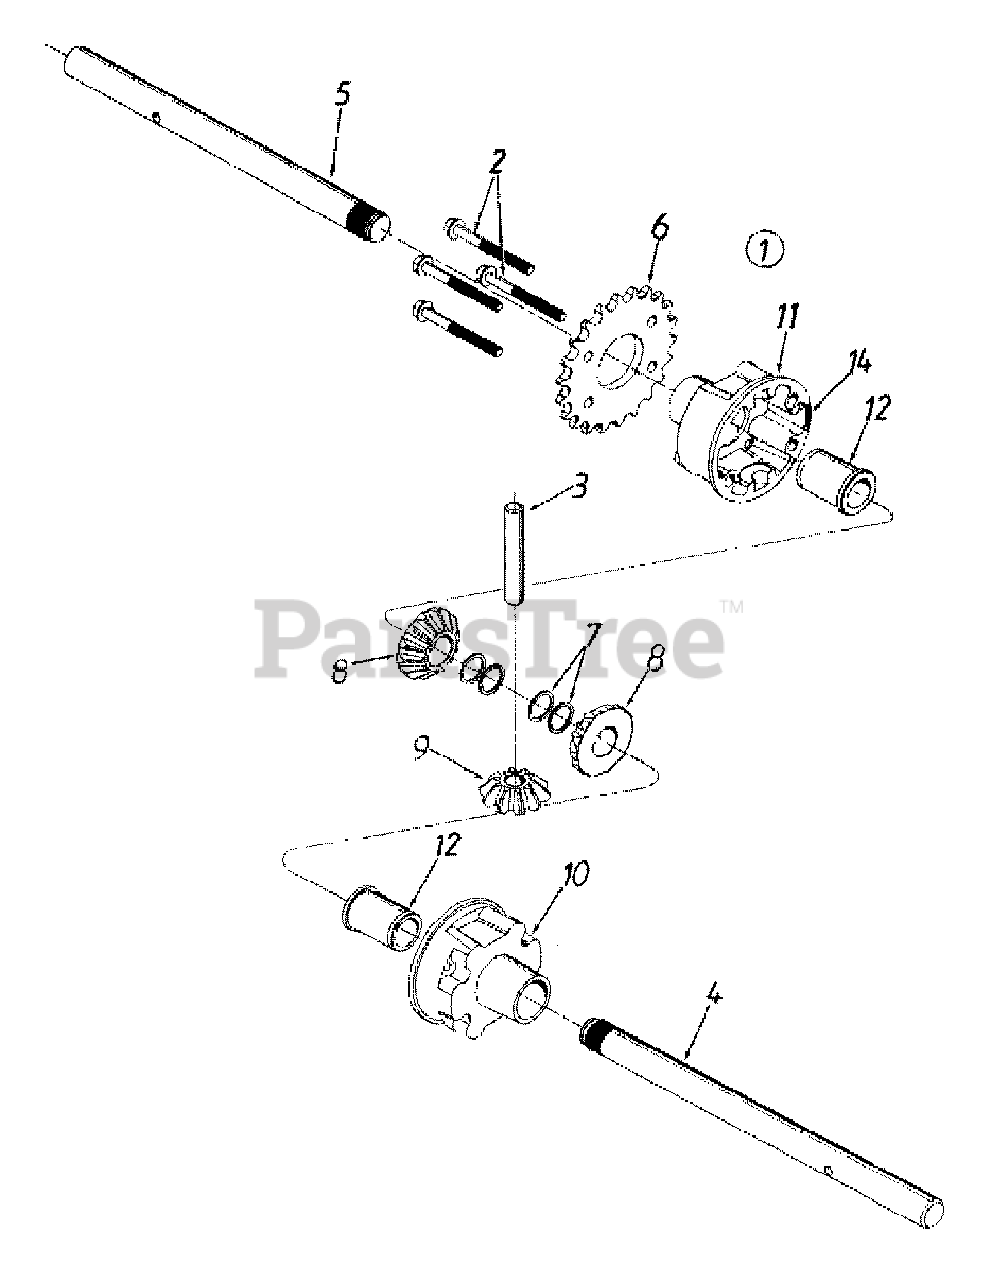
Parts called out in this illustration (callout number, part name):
1	DIFFERENTIAL ASSY COMPLETE
2	SCREW-HEX
3	SHAFT-CROSS
4	AXLE-SHAFT 10.95" LONG
5	AXLE-SHAFT 9.82" LONG
6	SPROCKET 22 T
7	RING-RETAINING (2 PER AXLE)
8	GEAR-DIFFERENTIAL 14T
9	GEAR-DIFFERENTIAL 10T
10	HOUSING-DIFFERENTIAL RH
11	HOUSING-DIFFERENTIAL LH
12	BEARING-FLANGE
